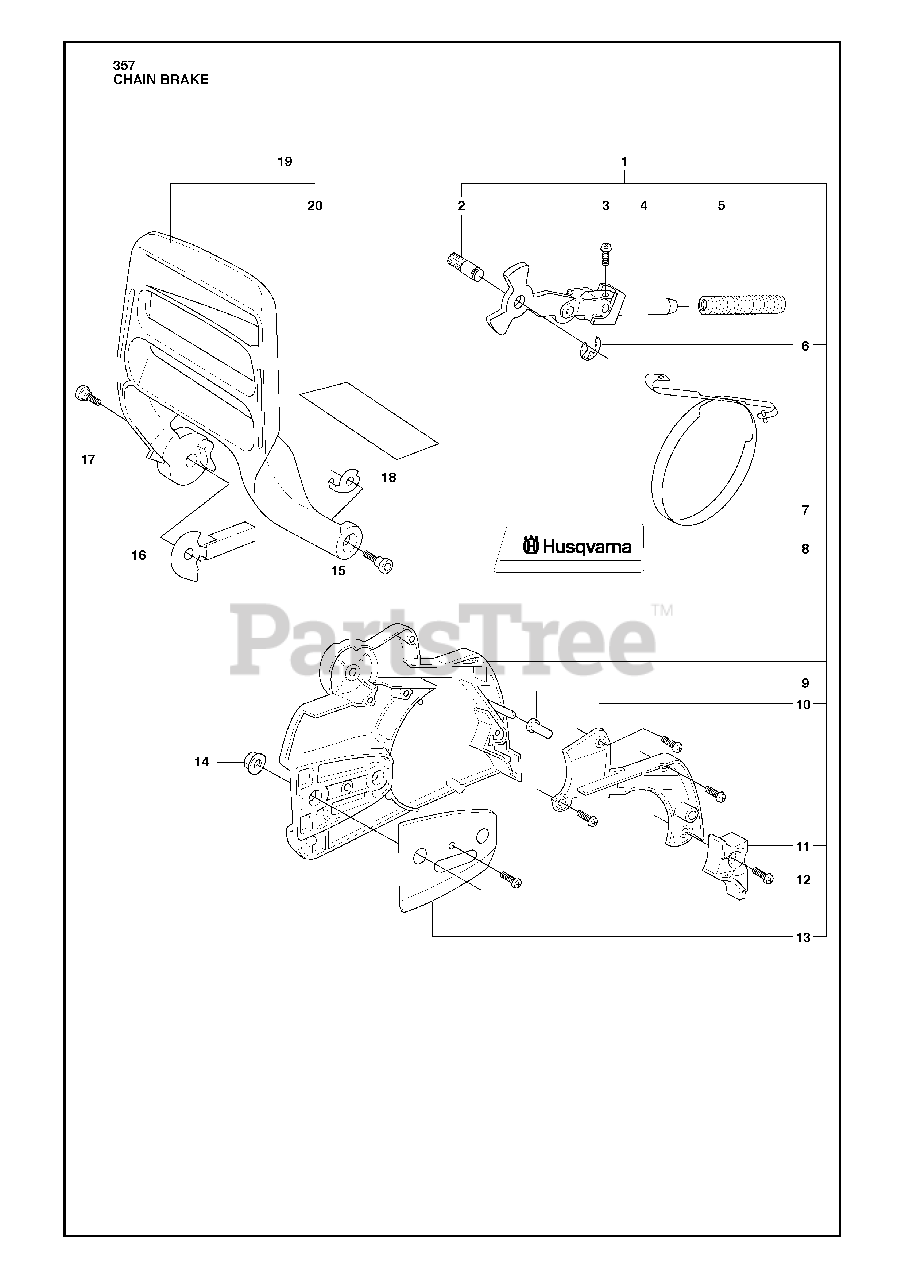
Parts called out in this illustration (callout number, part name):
1	CHAIN BRAKE
7	BRAKE BAND
14	NUT M8 FLANGE
20	PROTECTOR
